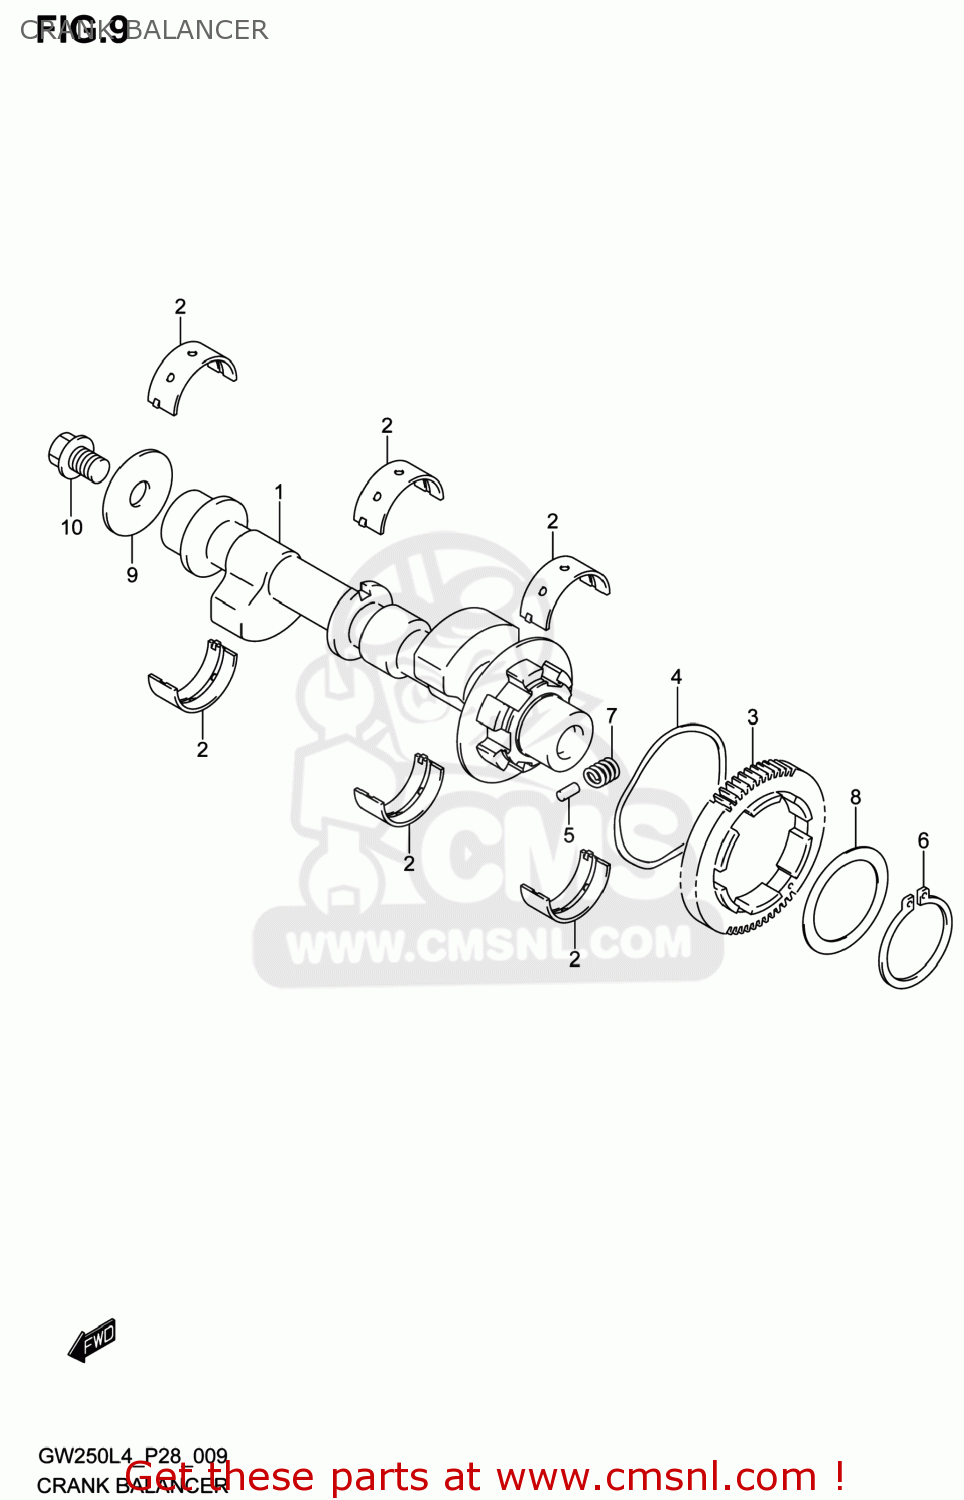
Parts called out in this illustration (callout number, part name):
1	BALANCER,CRANK
2	BEARING,CRANK BALANCER
3	GEAR,CRANK BALANCER DRIVEN
4	WASHER
5	PIN(4.5X9.5)
6	CIRCLIP
7	SPRING
8	WASHER
9	WASHER(10X37X3)
10	BOLT
